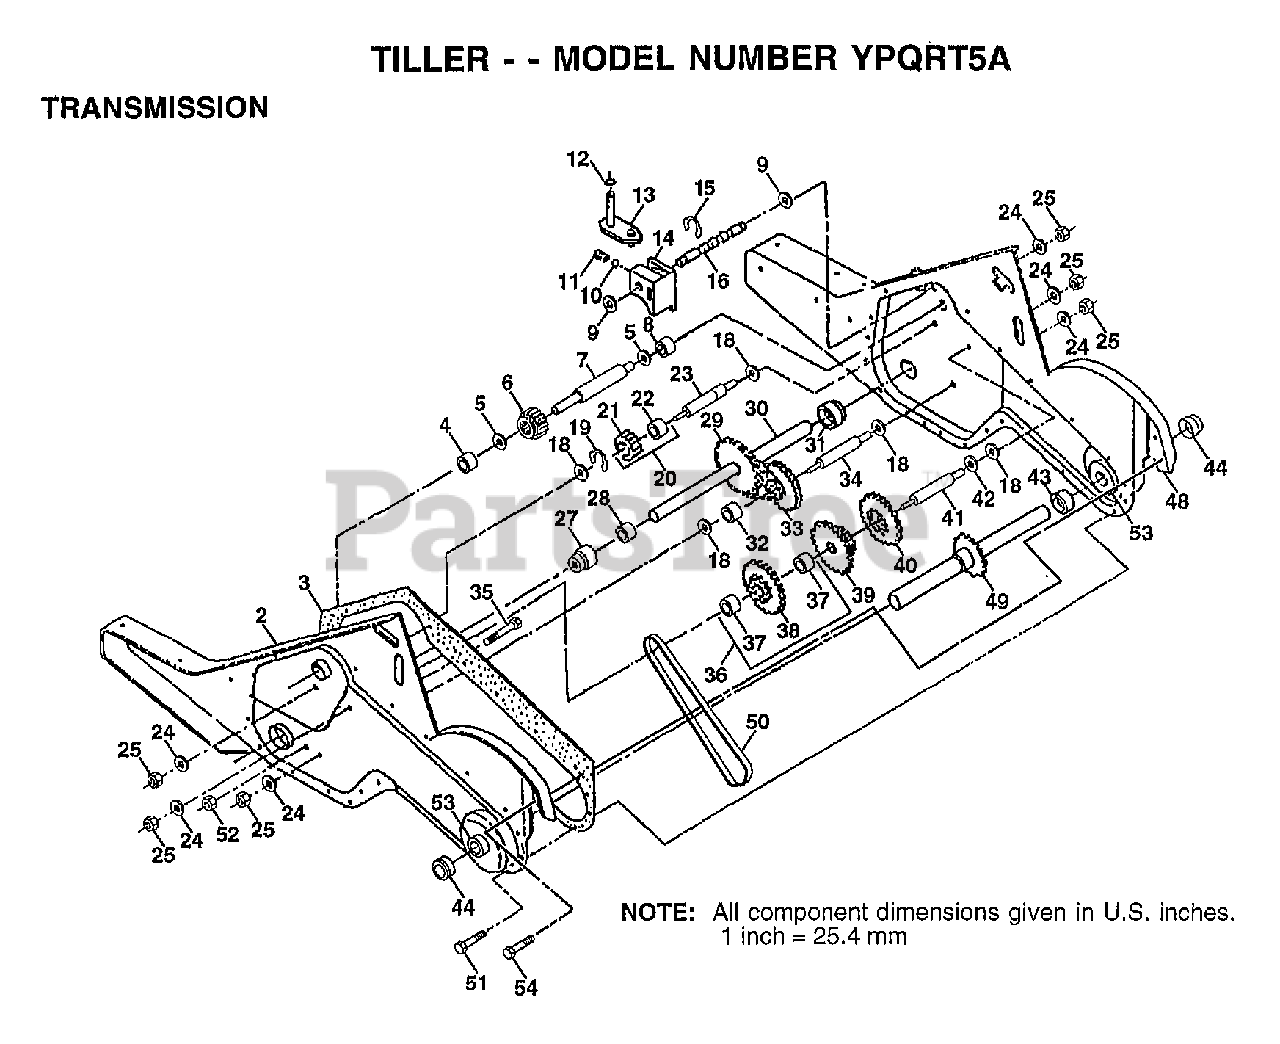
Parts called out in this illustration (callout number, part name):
2	GEARCASE LH W/BEARING
3	GASKET.GEARCASE
4	NEEDLE BRNG LT
5	"T, BEARING"
6	GEAR PINION INPUT
7	"SHAFT.INPUT.""D"""
8	"TI, BEARING"
9	WASHER SEAL
11	SPRING-SHIFT CRT
12	O-RING TI
13	BRACKET ASM SHIFT
14	SHIFT FORK TI
15	KLIP RING
16	SHAFT.SHIFTER
18	WASHER
19	KLIP RING
20	GEAR ASSY CRT
21	GEAR-REV IDLR CRT
22	NEEDLE BEARING TI
23	SHAFT CRT
24	LOCKWASHER
25	NUT.ASF.HEX.7/16
27	BEARING.SHAFT.LH.
28	BUSHING TI
29	CHAIN CRT
30	GROUND SHAFT ASSY
31	BEARING.SHAFT.RH.
32	SPACER TI
33	SPRCKT 8 GEAR CRT
34	SHFT 2ND RED. CRT
35	SCRW WHIZ LOK CRT
36	SPROCKET.ASM.W/BR
37	BEARING
39	GEAR TI
40	GEAR TI
41	REDUCTION SHFT TI
42	BRNG RACE
43	SPACER TI
44	SEAL ASM-OIL
48	GEARCASE RH W/BEARING
49	TINE SHAFT
50	CHAIN.50 LINK TI
51	SCREW
52	NUT.HEX.5/16-18
53	KIT.BEARING
54	SCREW 1/4-20X3/4
